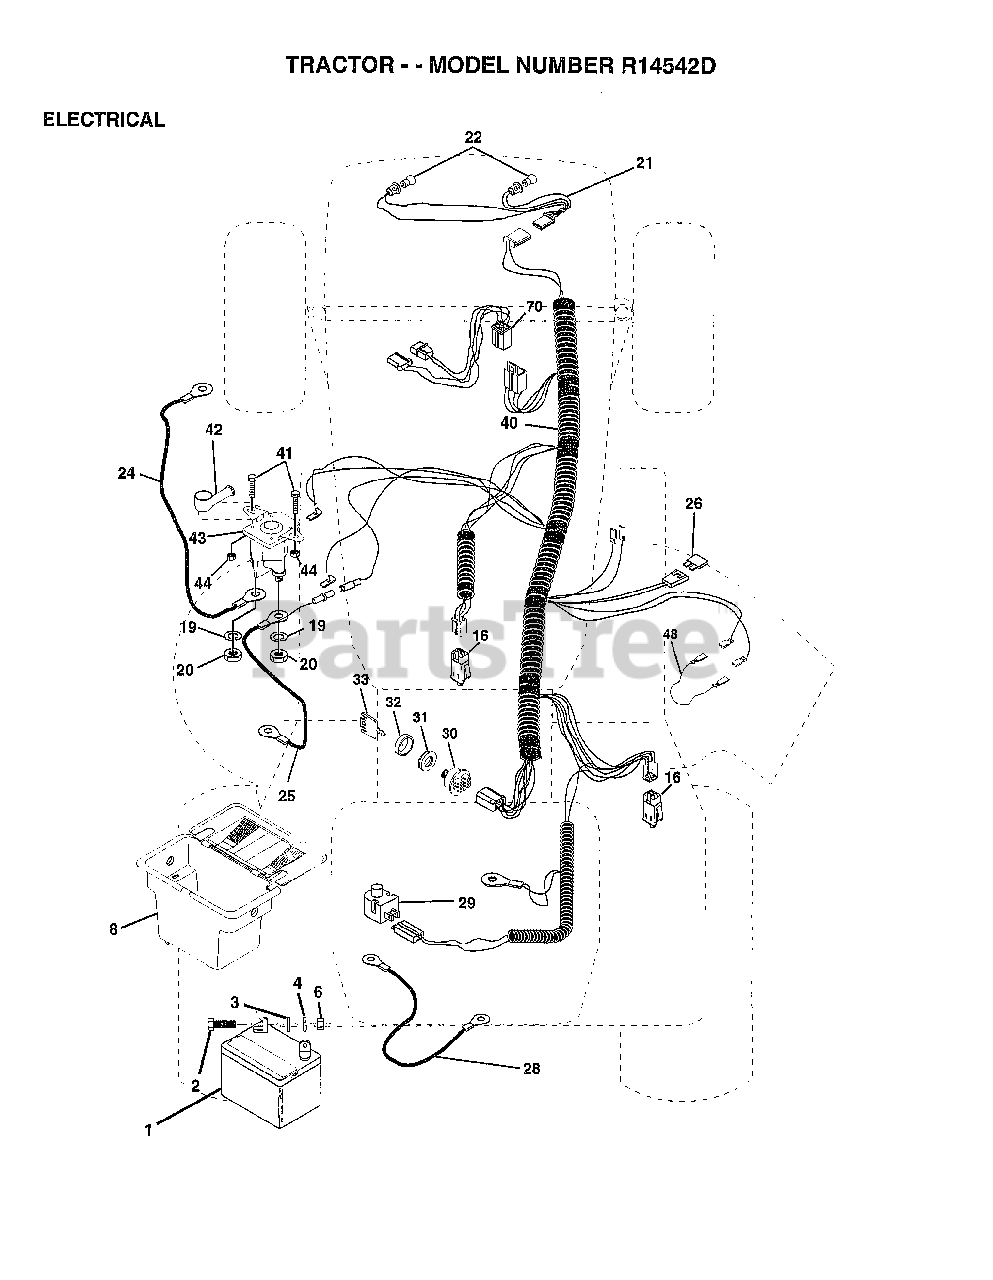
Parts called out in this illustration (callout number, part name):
3	WASHER
4	LOCKWASHER
8	"CASE,BATTERY.MECH"
16	SWITCH INTERLOCK
20	NUT
21	"HARNESS,LIGHT SOC"
22	HEADLAMP BULB
24	CABLE.BTRY.6GA.RD
25	CABLE.BTRY.6GA.38
26	FUSE HYT
28	CABLE T
29	SWITCH SEAT
30	SWITCH IGN 4POS
31	NUT IGNITION
32	COVER KEY SWITCH
33	KEY
40	HARNESS IGNITION
41	BOLT HXHD FIN
44	NUT HXKEP 1/4X20
48	ADAPTER AMMETER
70	HARNESS.ENG.DUAL
